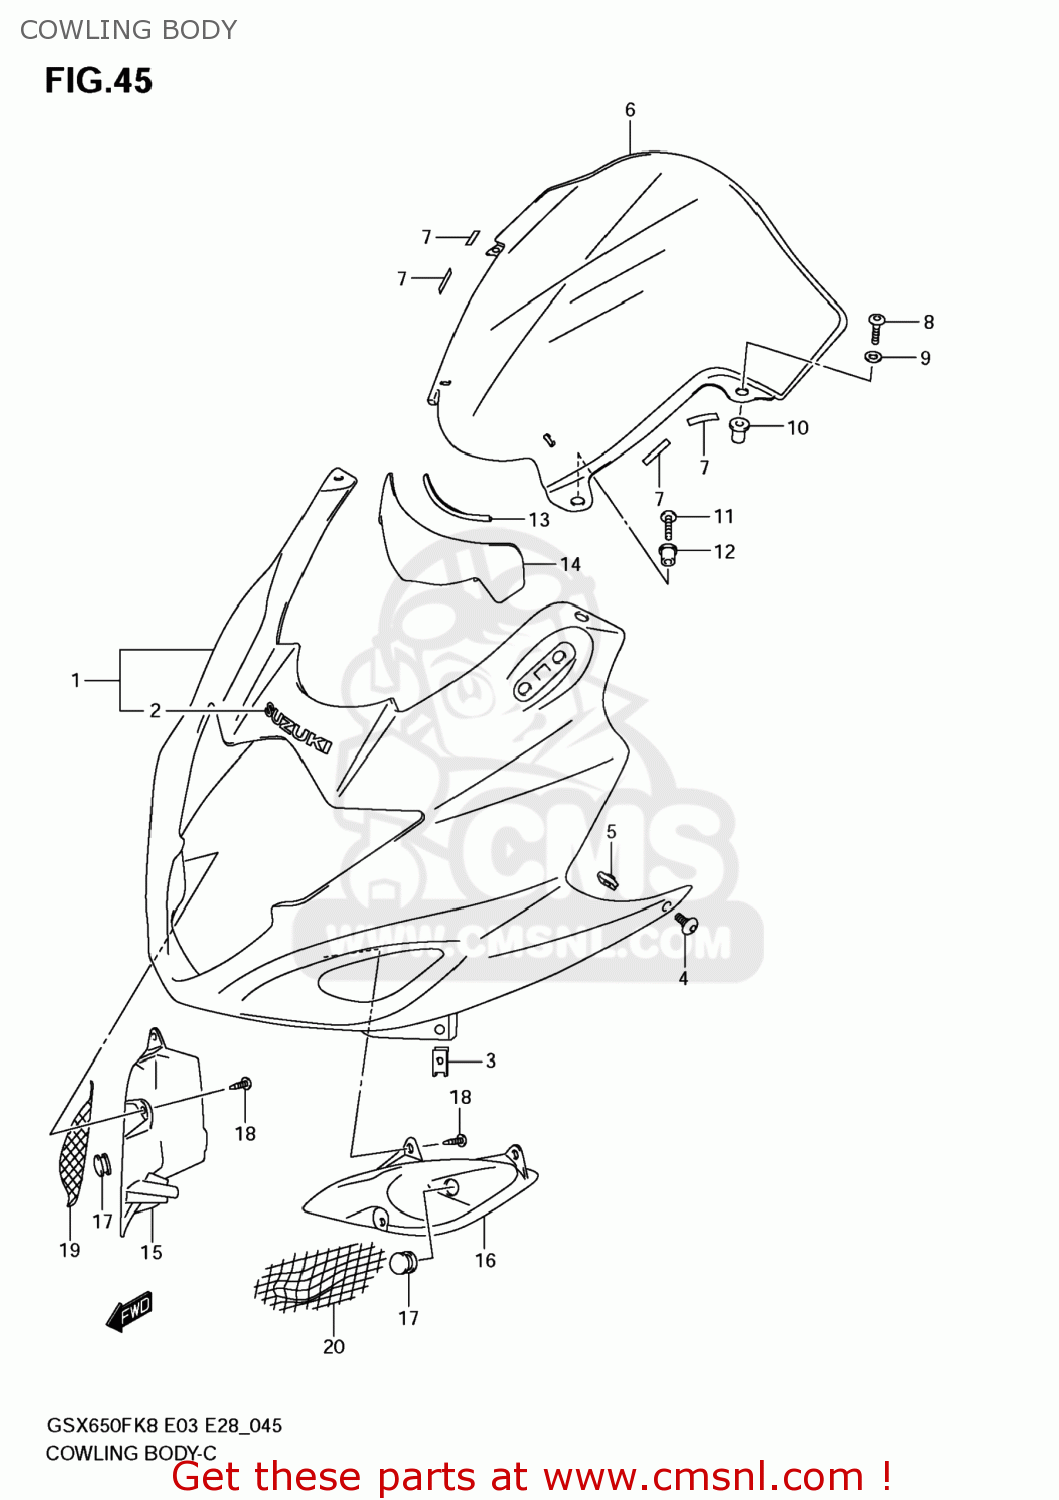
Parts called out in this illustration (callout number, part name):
1	BODY,COWLING(BLUE)
2	EMBLEM,SUZUKI
3	NUT,COWL
4	SCREW(5X16)
5	NUT
6	WINDSCREEN
7	TAPE(6X25X0.13)
8	SCREW(5X16)
9	WASHER
10	NUT
11	SCREW
12	NUT
13	CUSHION,WINDSCREEN
14	COVER,WINDSCRE
15	COVER,INTAKE,R
16	COVER,INTAKE,L
17	CAP,TANK RAIL
18	SCREW
19	NET,INTAKE,R
20	NET,INTAKE,L
